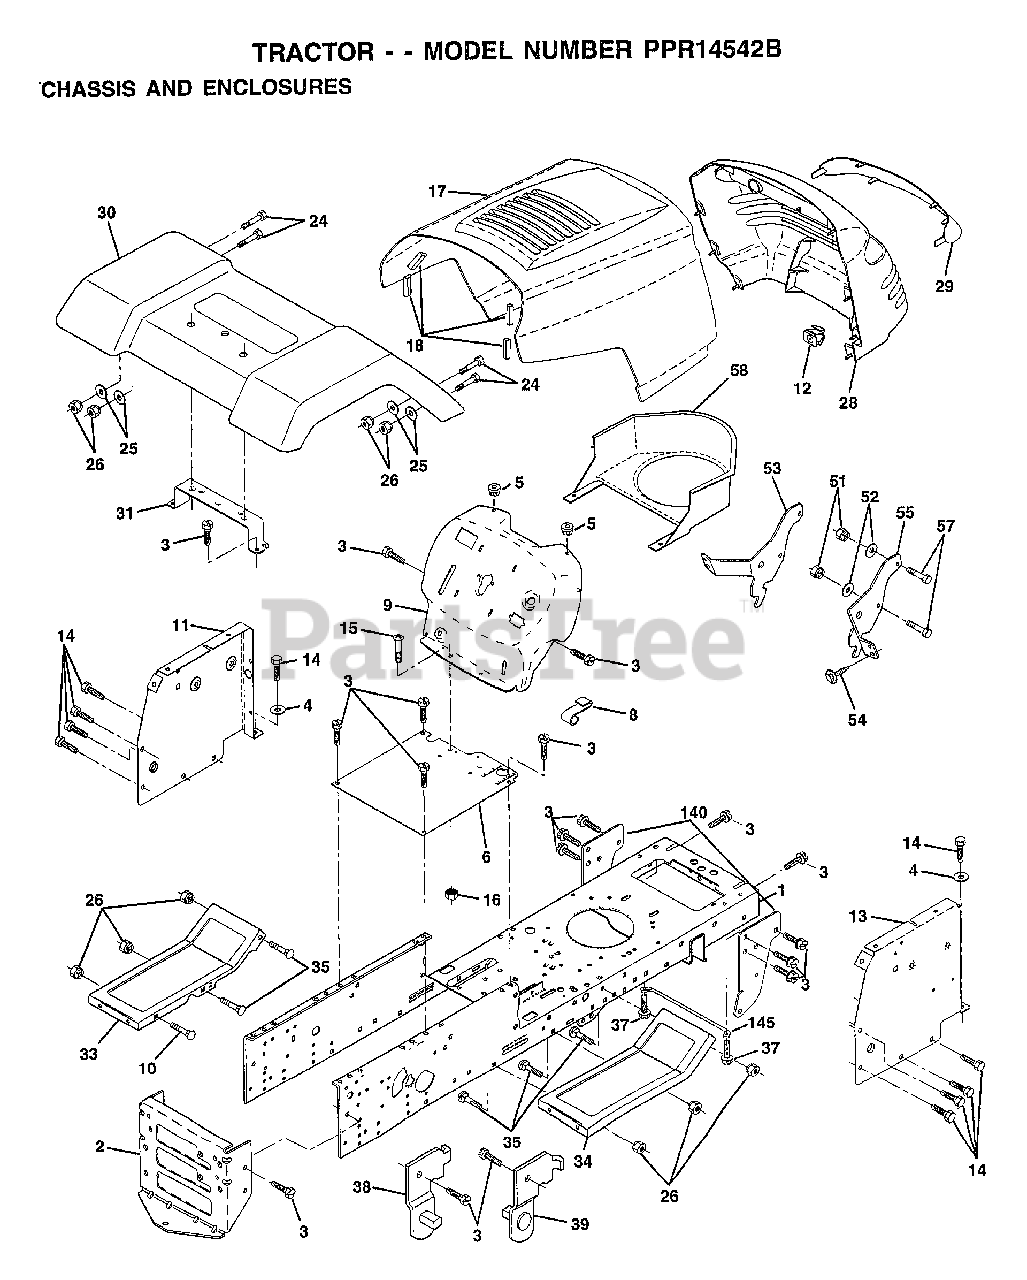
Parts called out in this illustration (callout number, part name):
1	CHASSIS.STAMPING
3	SCREW
4	WASHER
5	BUMPER-HOOD/DASH
6	SADDLE
8	CLIP.RETAINER
9	DASH.SILKSCREEN
11	"PANEL-DASH,LH"
12	CLIP.TINNERMAN
13	PANEL.ASM.SLKSCR.DASH.RH
14	SCREW LT
15	SCREW
17	HOOD.STEEL.ASSY
24	BOLT
25	WASHER
26	NUT
28	GRILL
29	GRILLE.LENS
30	FENDER ASM.
31	BRKT FENDER
33	FOOTREST PNT LH
34	FOOTREST.RH.LT/GT
35	BOLT
37	SCREW LT
38	BRACKET ASM LH
39	BRACKET ASM RH
51	NUT
52	WASHER
53	BRACKET.GRILLE.LH
54	SCREW.HEX.WS.HD
55	BRACKET.GRILLE.RH
58	AIR DUCT
140	BRKT SUSPENSION
145	"ROD POVOT,CHASSIS"
